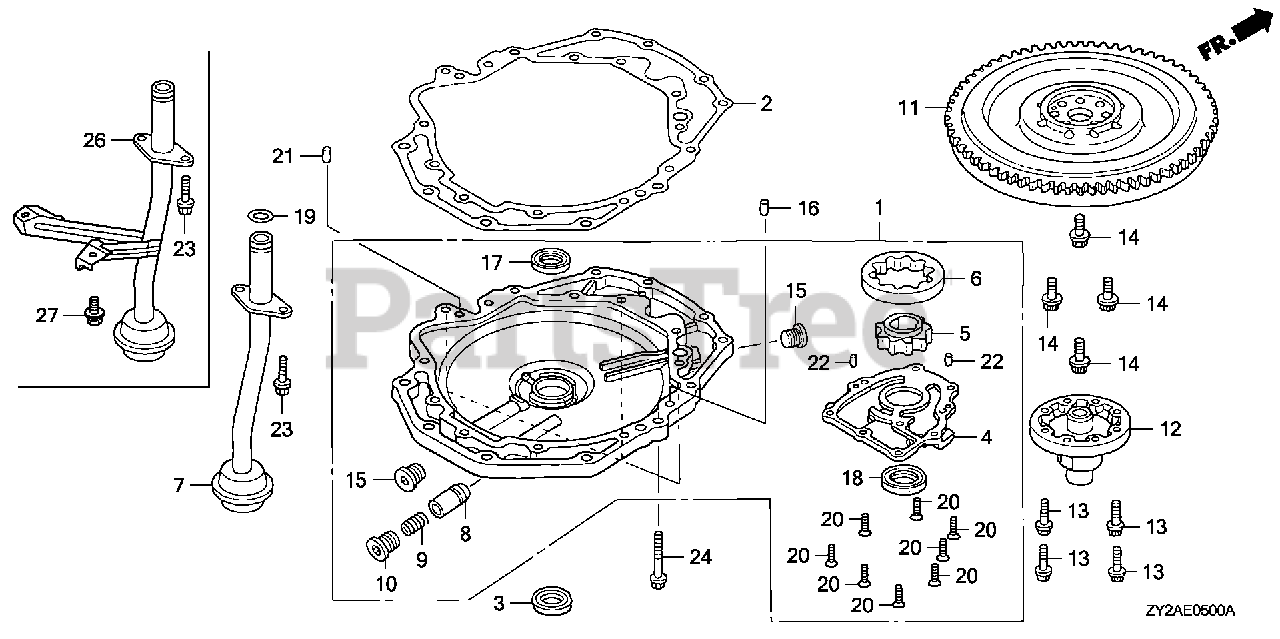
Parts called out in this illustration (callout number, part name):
1	PUMP ASSY., OIL *NH8* (DARK GRAY)
2	GASKET, OIL PUMP BODY
3	RUBBER, OIL PUMP
4	COVER, OIL PUMP
5	ROTOR, OIL PUMP (INNER)
6	ROTOR, OIL PUMP (OUTER)
7	STRAINER, OIL
8	VALVE, RELIEF
9	SPRING, RELIEF VALVE
10	BOLT, SEALING (18MM)
11	FLYWHEEL *TBLACK* (BLACK)
12	BOSS, FLYWHEEL
13	BOLT, SPECIAL (8MM)
14	BOLT, FLANGE (12MM)
15	BOLT, SEALING (22MM)
16	PIN, DOWEL (14X15)
17	OIL SEAL (46X60X9)
18	OIL SEAL (31X46X7) (NOK)
19	O-RING (20.6X2.6)
20	SCREW, FLAT (6X16)
21	PIN B, DOWEL (10X16)
22	ROLLER (5X8)
23	BOLT, FLANGE (6X18)
24	BOLT, FLANGE (8X30)
26	STRAINER, OIL
27	BOLT, FLANGE (6X14)
